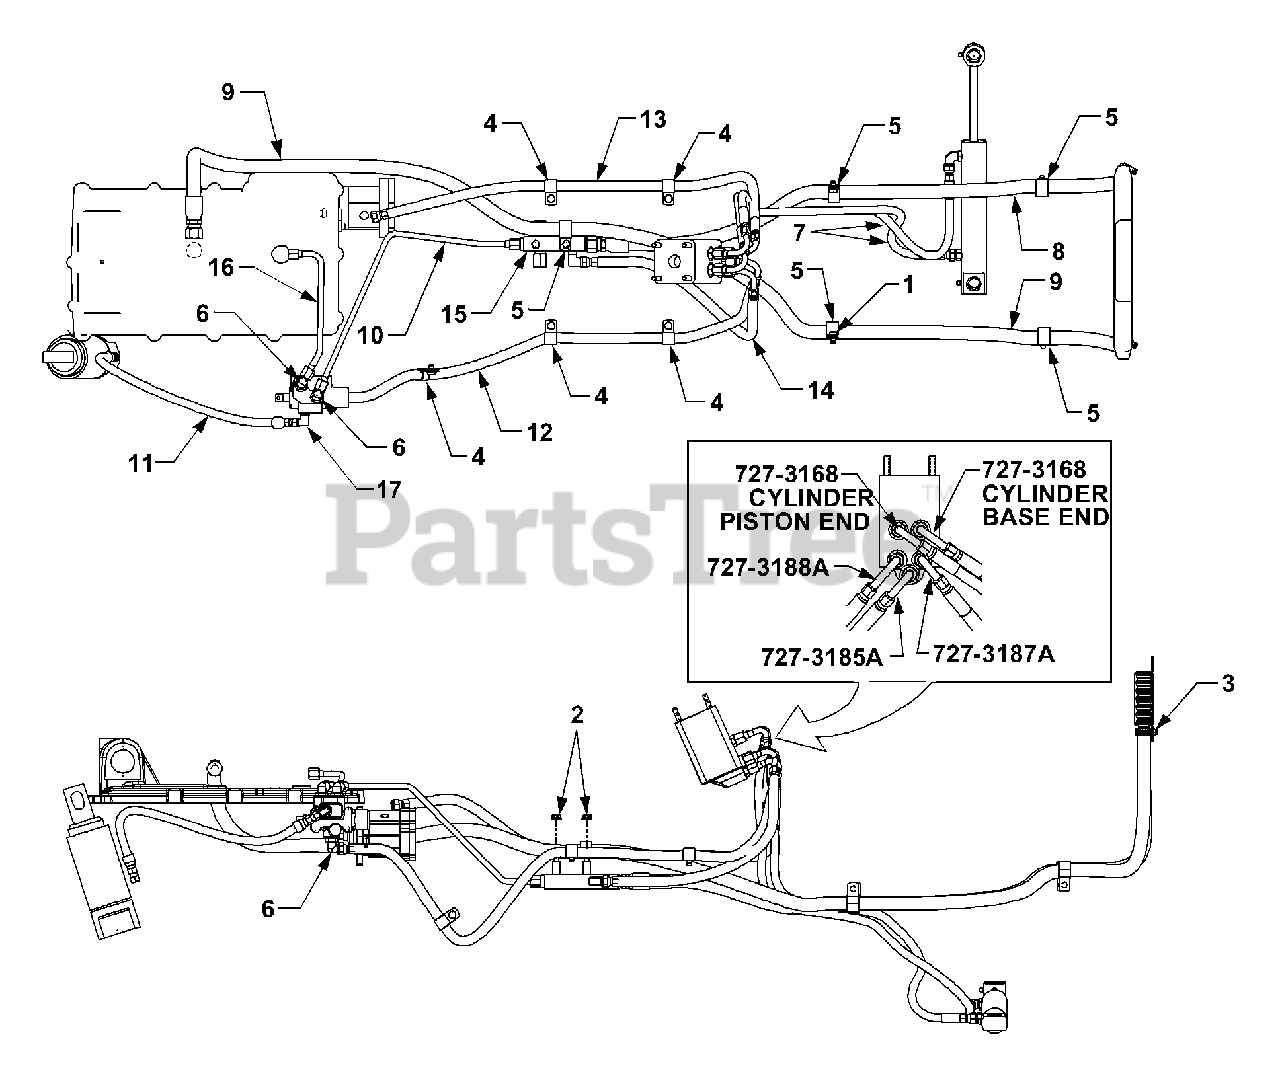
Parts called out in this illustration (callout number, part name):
1	Screw, Hex Wash Hd. Tapp 5/16-18 x .5
2	Nut, Hex Flange Lock, 5/161-18 GR5
3	Clamp, Adjustable Hose
4	Clamp, Hose
5	Clamp, Hose
6	Fitting, 90 Degree
7	Hose, Steering
8	Tube, Oil Cooler Return
9	Hose, Oil Return
10	Tube, Lift Return Line
11	Hose, Lift Cylinder
12	Hose, Lift Inlet
13	Hose, Steering Pressure
14	Hose, Steering Tank
15	Manifold, Return
16	Tube, Cylinder Return
17	Fitting, 90 Degree
